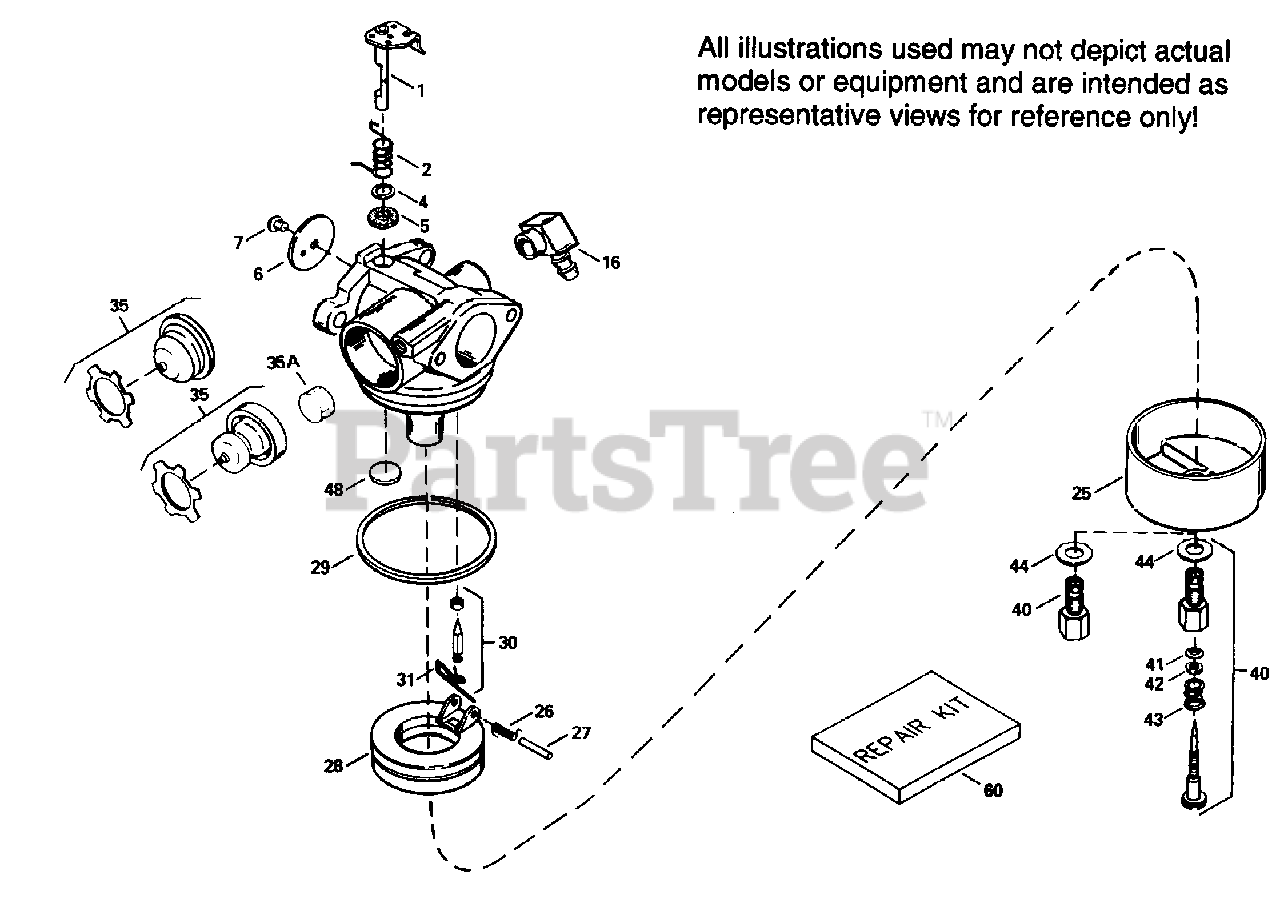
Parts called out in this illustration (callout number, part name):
1	Throttle Shaft & Lever Assembly
2	Throttle Return Spring
4	Dust Seal Washer
5	Dust Seal (Throttle)
6	Throttle Shutter
7	Shutter Screw
16	Fuel Fitting
25	Float Bowl
27	* Float Shaft
28	Float (Plastic)
29	* Float Bowl "O" Ring
30	* Inlet Needle, Seat, & Clip (Incl. 31)
31	Spring Clip
35	Primer Bulb/Retainer Ring
40	* Main Adj. Screw Ass'y. Incl. 41 thru4 4
41	* High Speed Mixture Screw "O" Ring
42	High Speed Mixture Screw Washer
43	High Speed Mixture Screw Tension Spri ng
44	* Bowl Nut Washer
48	* Welch Plug, Atmospheric Vent
60	Repair Kit (Incl. items marked PK in notes) Incl. part #'s 27110 (1),27554 (1), 630740 (1), 630748 (1),631021 ( 1), 631022 (1), 631024 (1),631027 (1) , 631028 (1), 631838 (1),632234 (1)
